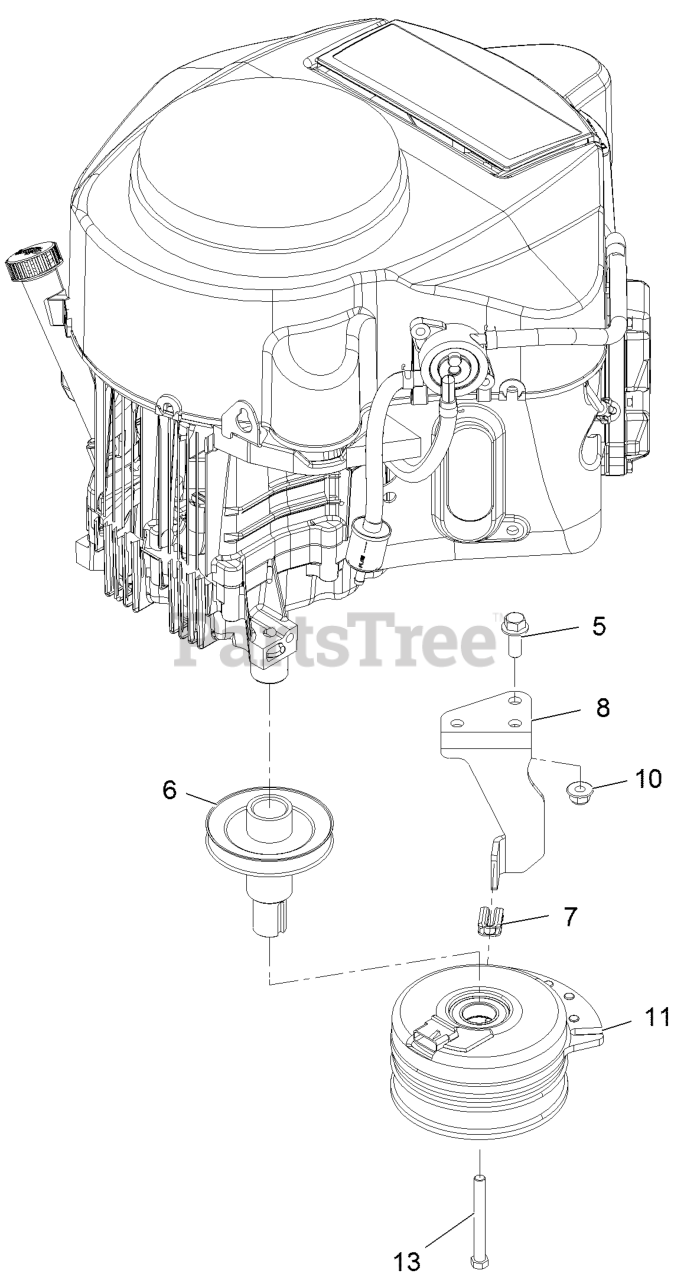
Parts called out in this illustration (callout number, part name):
5	SCREW-HHF 3/8-16 X 1
6	PULLEY-ENGINE
7	ISOLATOR-CLUTCH
8	STOP-CLUTCH (NARROW)
10	NUT-HF, NI
11	CLUTCH-ELECTRIC
13	PIN-ROLL, SLOTTED
